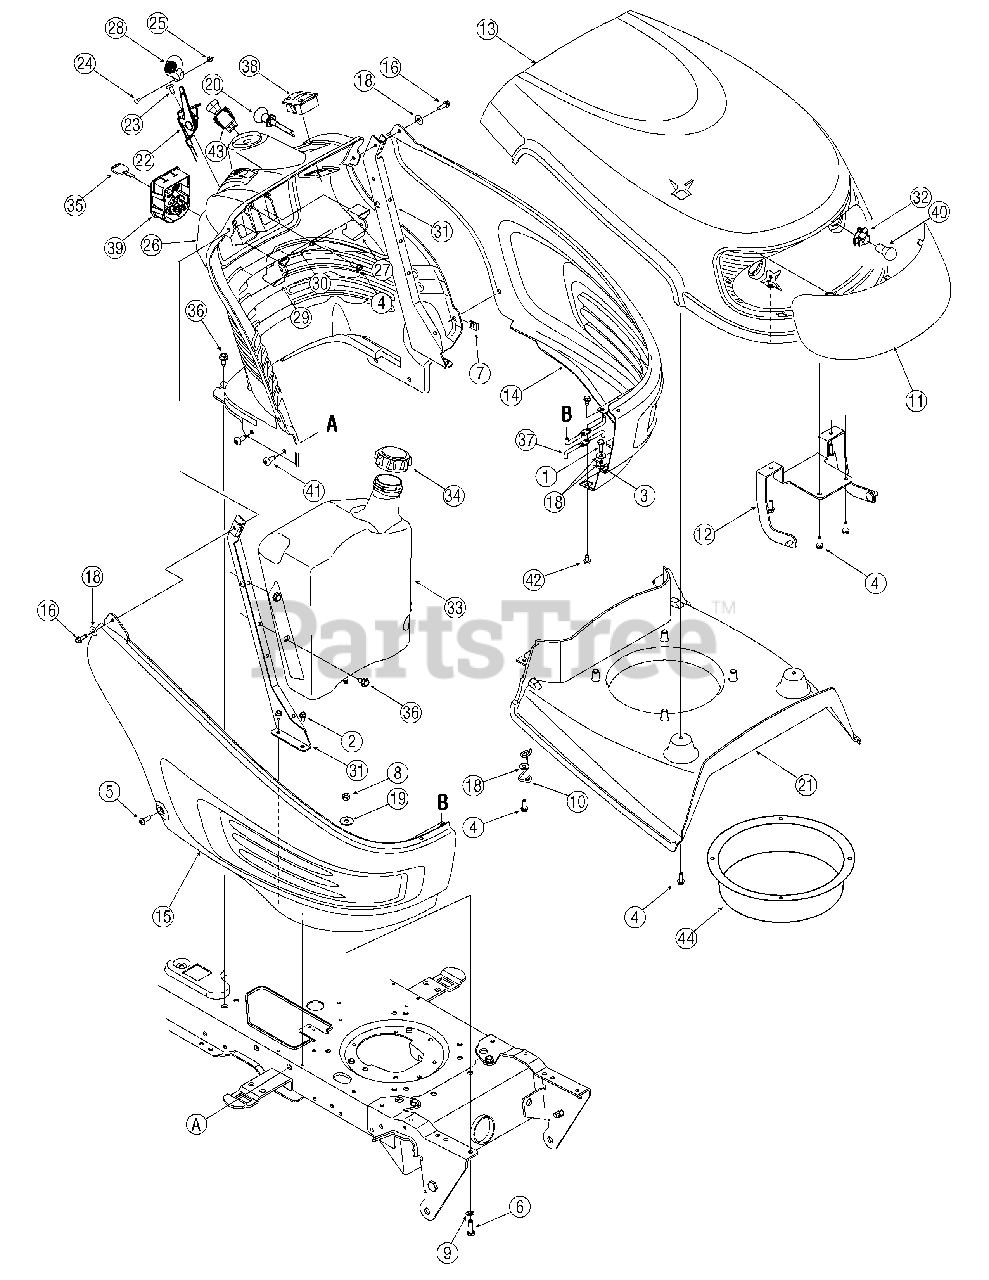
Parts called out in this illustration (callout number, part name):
1	Hex Cap Screw, 1/4-20 x .75
2	Self-tapping Screw, 1/4-20 x .5
3	Flange Lock Nut, 1/4-20
4	Self-tapping Screw, 1/4-15 x .75
5	Pan Phillips Screw, 1/4-20 x .75
6	Hex Cap Screw, 5/16-18 x 1.0
7	U-type Speed Nut, 1/4-20
8	Flange Lock Nut, 5/16-18
10	Hood Latch Rod
11	Head Light Lens
14	LH Side Panel
15	RH Side Panel
16	Screw, 1/4-20 x .750
17	Flat Washer, .283 x .75 x .030
18	Flat Washer, .28 x .74 x .063
19	Flat Washer, .349 x 1.0 x .063
20	Choke Control
21	Hood Plenum w/o Intake
22	Throttle Control/Cable
23	Torx Self-Tapping Screw
24	Torx Screw, #8-32 x .375
25	Hex Nut, 8-32
26	Dash Panel, 4/6-style w/Cargo Net
27	Parking Brake Button
28	Throttle Control Knob
29	Cruise Control Button
30	Brake/Cruise Pivot Rod
32	Lamp Socket
33	Fuel Tank, 3-gallon
34	Fuel Cap
35	Ignition Key w/ plastic cover
35	Ignition Key w/o plastic cover
36	Self-tapping Screw, 5/16-18 x .75
37	Side Panel Support
38	Systems Indicator Monitor
39	Ignition Switch
40	Miniature Lamp, 12V
41	Self-tapping Screw, 5/16-18 x .75
42	Screw 1/4-20
43	Electric PTO Switch
44	Intake Bellow
